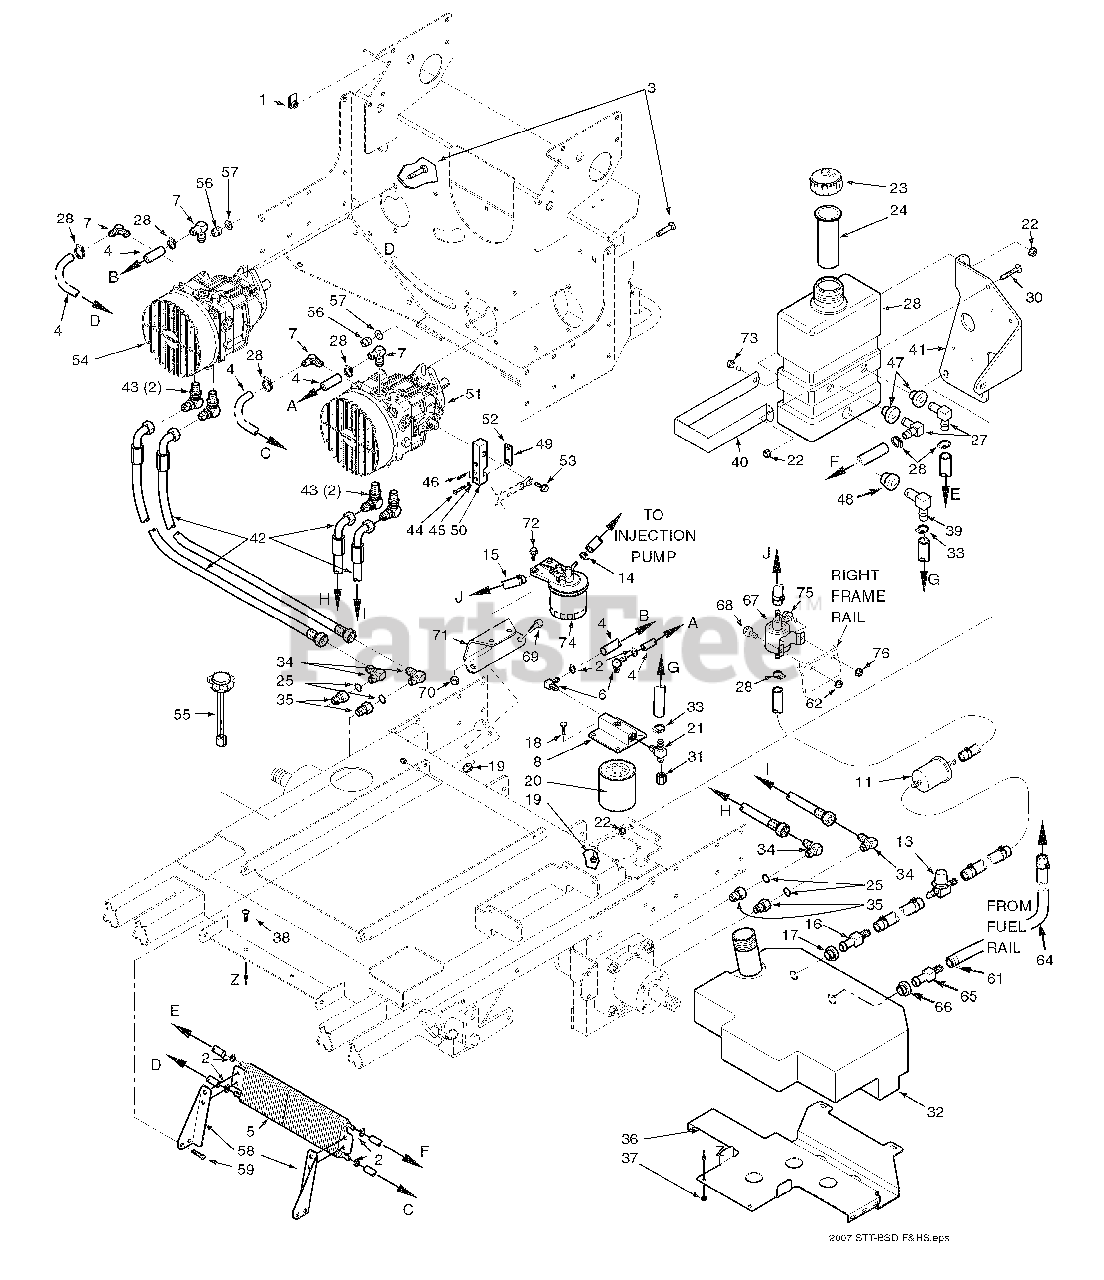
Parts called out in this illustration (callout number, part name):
1	U-Nut 1/4-20
2	Hose Clamp, 0.69 dia.
3	Bolt, Hex Head 1/4-20 x 2.0”
4	Hose, 3/8” ID Pushlock
5	Oil Cooler
6	Elbow, 90 Degree - 1/4 NPT x 3/8 Hose
7	Elbow, 90 Degree - 9/16 O-ring x 3/8 Hose
8	Oil Filter Base
9	Hose Assembly, 1/2” ID
10	Clamp, .87 max Dia.
11	Fuel Pre-Filter, Kubota
12	Fuel Hose, 5/16” ID.
13	Valve, Shutoff
14	Clamp, Fuel Hose
15	Fuel Hose, 5/16” ID.
16	Hose Fitting
17	Bushing
18	Bolt, Hex Head 5/16-18 x1.0” Zinc
19	Nut, Serrated Flange 5/16-18
20	Oil Filter
21	Tee, 3/4 O-ring x JIC x 1/2” Hose
22	Nut, Hex Elastic Stop 1/4-20
23	Cap, Hydraulic Tank
24	Insert, Filler Neck
25	O-Ring
26	Oil Reservoir Assembly
27	Elbow, 90 Degree .38 Hose
28	Hose Clamp, 0.69 dia.
29	Hose, 3/8” ID, Pushlock
30	Screw, Phillips Head, 1/4-20
32	Fuel Tank Assembly
33	Clamp, Hose
34	Elbow, 90 Degree, 7/8-14 THD
35	Bushing, 7/8-14 JIC x 3/4-16 O-Ring
36	Support Bracket, Fuel Tank
37	Nut, 5/16-18 Serrated Flange
38	Bolt, Carraige 1/4-20 x 3/4”
39	Elbow, 90 Degree
40	Strap, Hydraulic Tank
41	Support Bracket, Hydraulic Tank
42	Hose Assembly, Pump
43	Union, 3/4-16 JIC x 3/4-16 O-ring
44	Bolt, Hex Head, 1/4-20 x 1-14”
45	Lockwasher, 1/4” Spring
46	Roll Pin, Spring 3/16 x 3/4”
47	Bolt, Hex Serrated Flange, 1/4-20 x 3/4”
48	Fuel Hose, 5/16” ID.
49	Clamp Plate, Pump Control
50	Block, Pump Control
51	Pump, Left Hand, BDP-16A
52	Nut, Hex, Elastic Stop 3/8-16
53	Bolt, Hex Head, 3/8-16 x 1-1/4
54	Pump, Right Hand, BDP 16A
55	Cap, Fuel Tank W/Gauge
56	Nut, Hex Elastic Stop 3/8-16
57	Flatwasher, 3/8” Grade 8
58	Mounting Bracket - LH, Oil Cooler
59	Bolt, Hex Head 5/16-18 x 3/4”
60	Cooler, Oil
61	Clamp, .69 Dia.
62	Nut, Serrated Flange 5/16-18
64	Hose, 1/4” Fuel Line
65	Fitting, Hose
66	Bushing
67	Fuel Pump, Kubota
68	Bolt, Hex Head 5/16-18 x 3/4”
69	Bolt, Hex Head 3/8-16 x 1”
70	Nut, Elastic Stop 3/8-16
71	Bracket, Fuel Filter Mounting
72	Bolt, Hex Head Serr. Flange 5/16-18 x 3/4”
73	Bolt, Hex Head 1/4-20 x 3/4”
74	Fuel Filter
75	Bolt, Hex Head 1/4-20 x 3/4”
76	Nut, Serrated Flange 1/4-20
